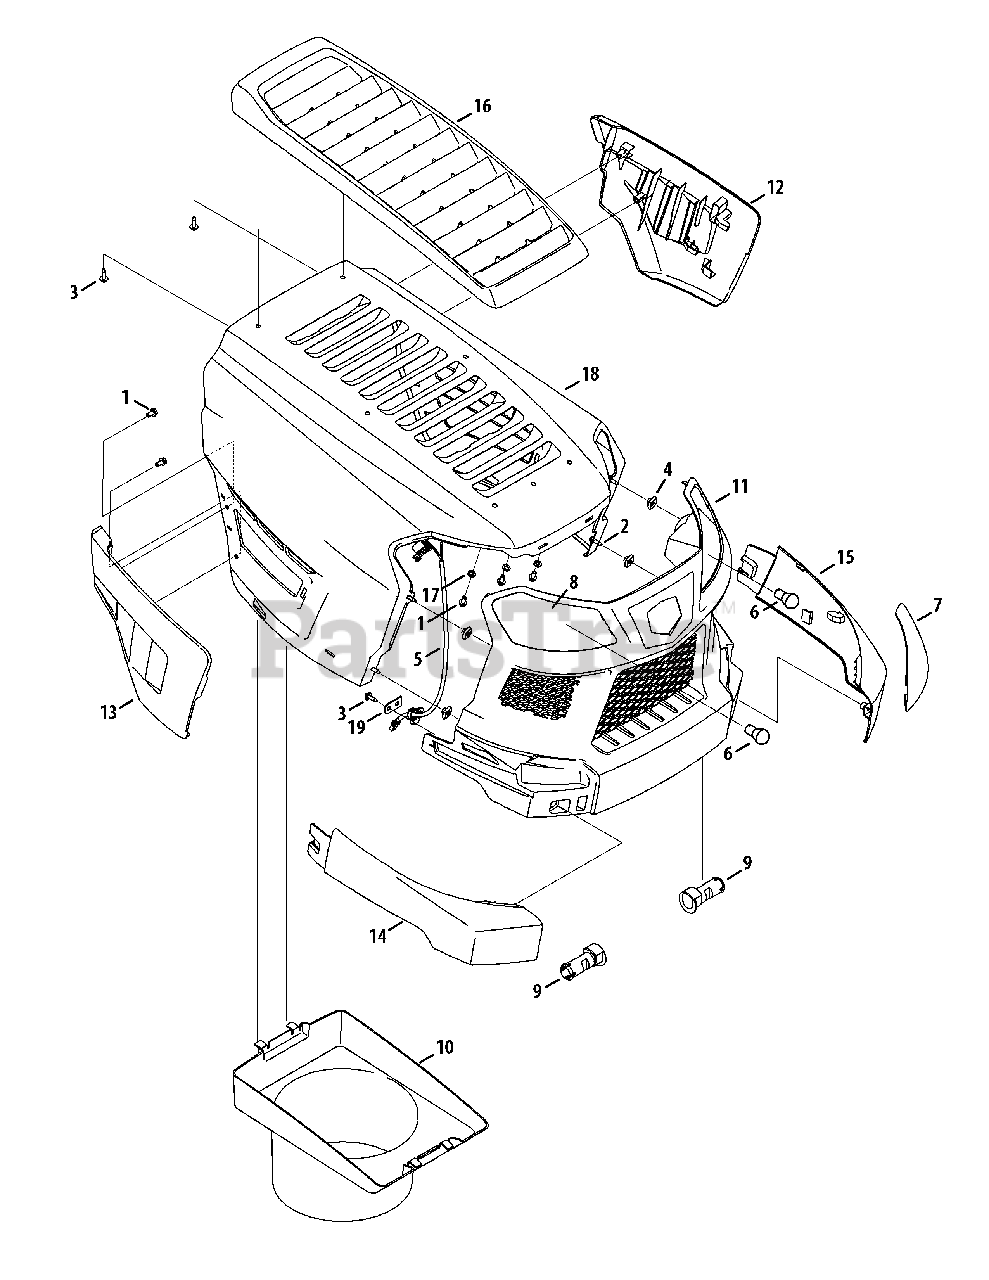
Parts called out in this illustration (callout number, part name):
1	Screw, 1/4-15 x 0.50
2	Hex Cap Screw, 1/4-20 x .625
3	Screw, 1/4 x .750
4	Nut, 1/4-20, .433 x .170
5	Headlight Harness
6	Miniature lamp 12V socket
7	Grill Lens - LH
8	Grill Lens - RH
9	Hood Pin
10	Plenum
12	Side Cover, LH
13	Side Cover, RH
14	Grill Panel, RH
15	Grill Panel, LH
16	Hood Scoop
17	Flat Washer, .281 x .500 x .063
18	Hood
19	Harness Bracket
